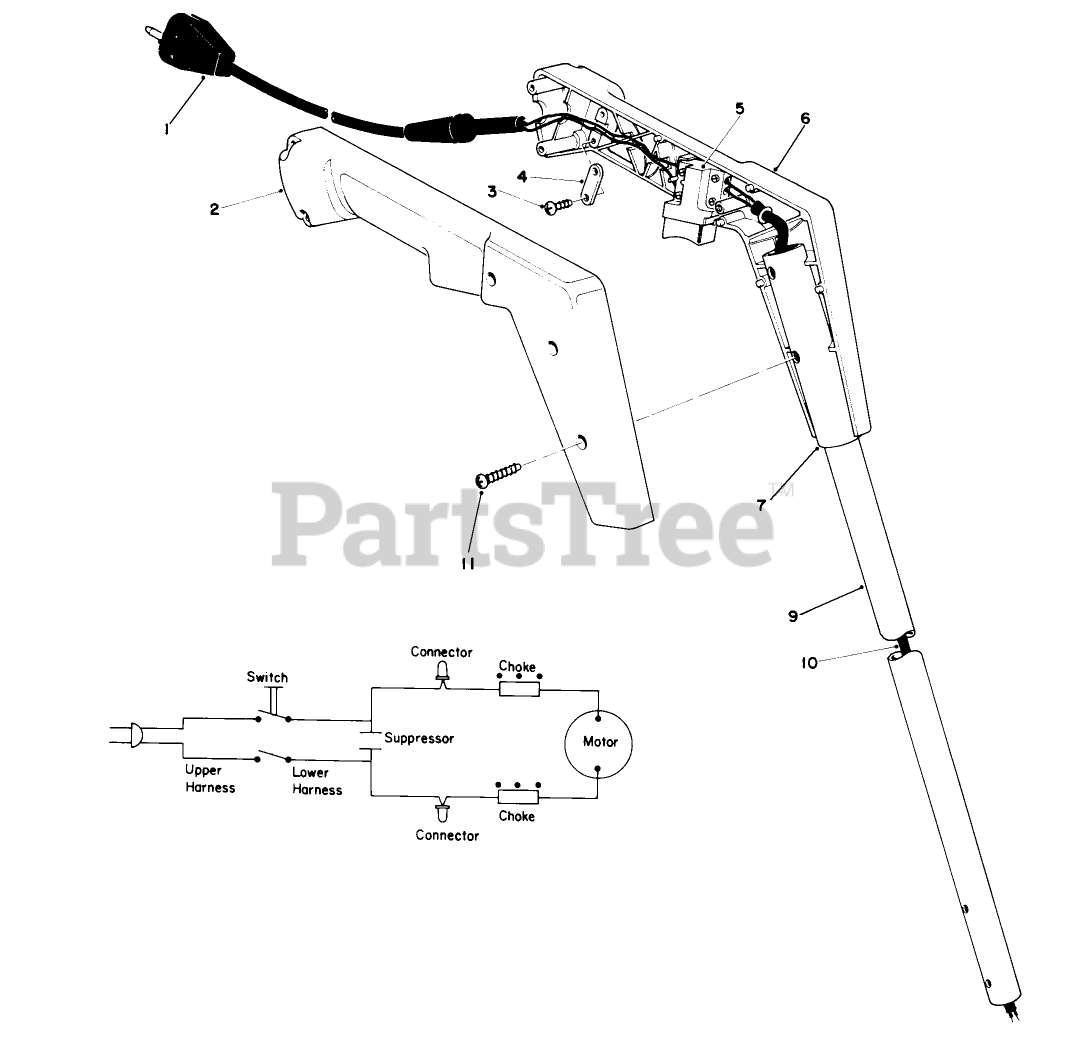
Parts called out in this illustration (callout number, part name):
1	Power Cord
2	Right Hand Grip
3	SCREW-PPH
4	Clamp
5	Switch
6	Left Hand Grip
7	Adapter Sleeve
10	Wire Harness
